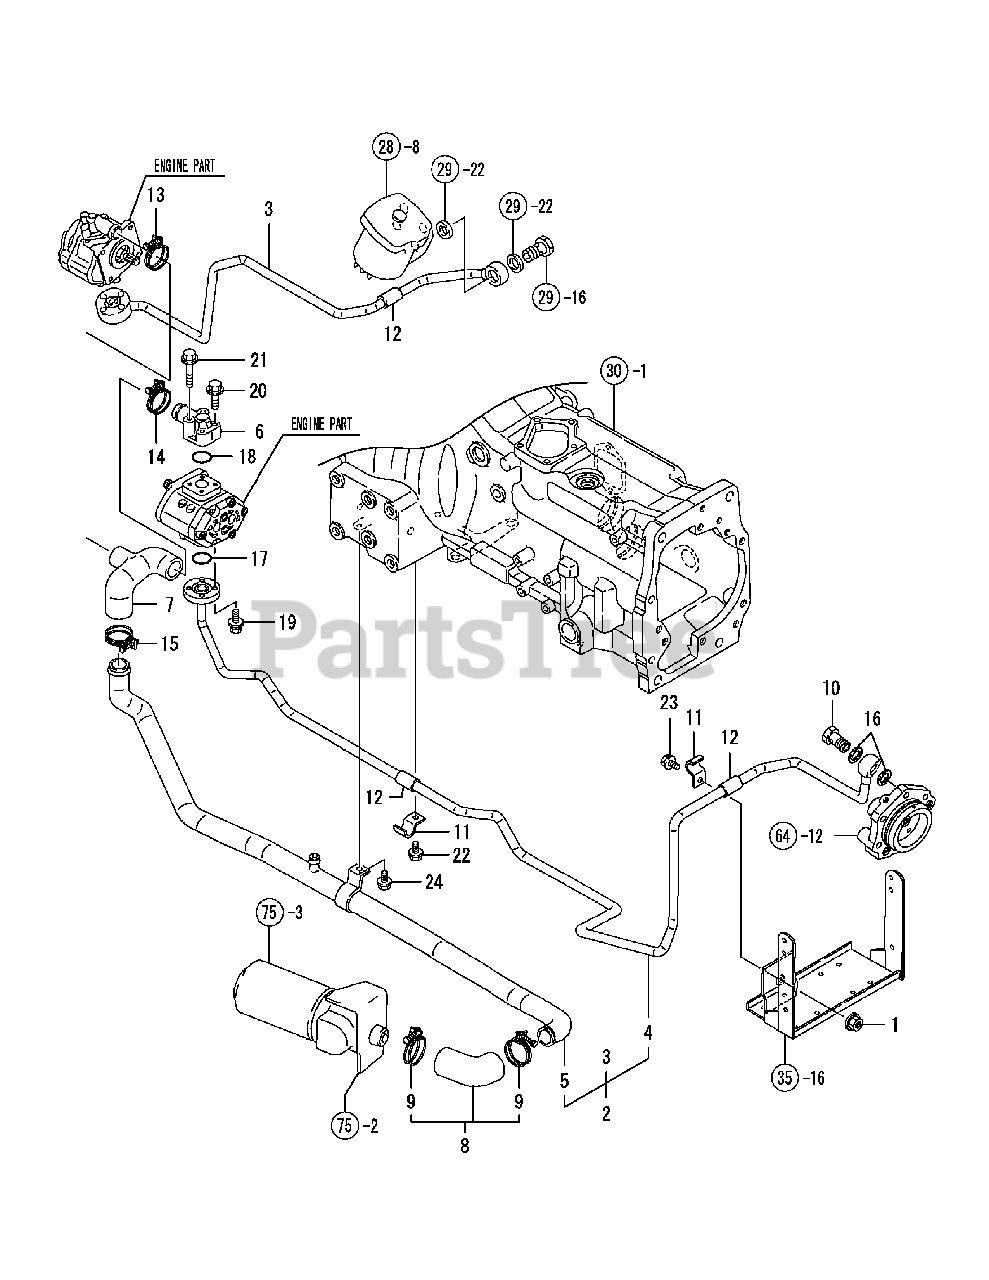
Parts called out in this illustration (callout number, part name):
1	NUT W/WASHER 8
4	LINE, PRESSURE
8	HOSE ASSY,SUCTION
10	CONNECTOR BOLT ASSY
17	O-RING 1A G-25.0
18	O-RING 1A S-25.0
20	BOLT M 6X 40 PLATED
21	BOLT M 6X 50 PLATED
22	BOLT M 8X 16 PLATED
23	BOLT M 8X 16 PLATED
24	BOLT M 8X 16 PLATED
